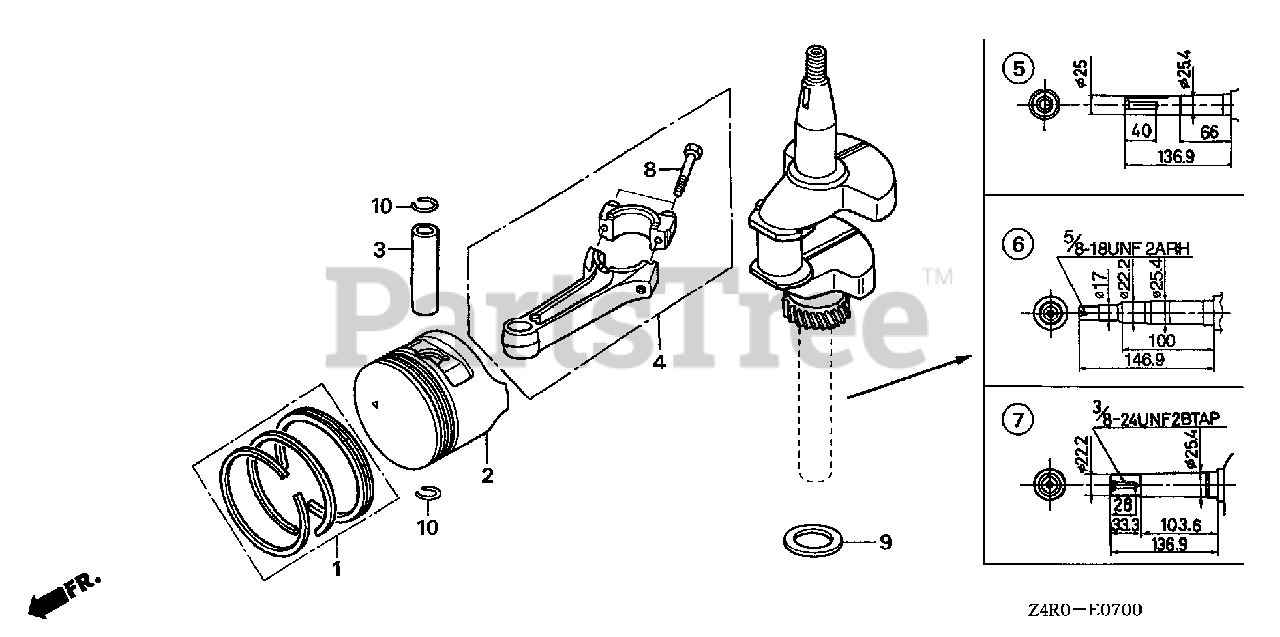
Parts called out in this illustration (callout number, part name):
1	RING SET, PISTON (STD) (TEIKOKU)
1	RING SET, PISTON (STD) (NIPPON)
1	RING SET, PISTON (0.25)
1	RING SET, PISTON (0.50)
1	RING SET, PISTON (0.75)
2	PISTON (STD)
2	PISTON (0.25)
2	PISTON (0.50)
2	PISTON (0.75)
3	PIN, PISTON
4	ROD ASSY., CONNECTING
5	CRANKSHAFT
8	BOLT, CONNECTING ROD
9	WASHER, THRUST (25.6MM)
10	CLIP, PISTON PIN (18MM)
